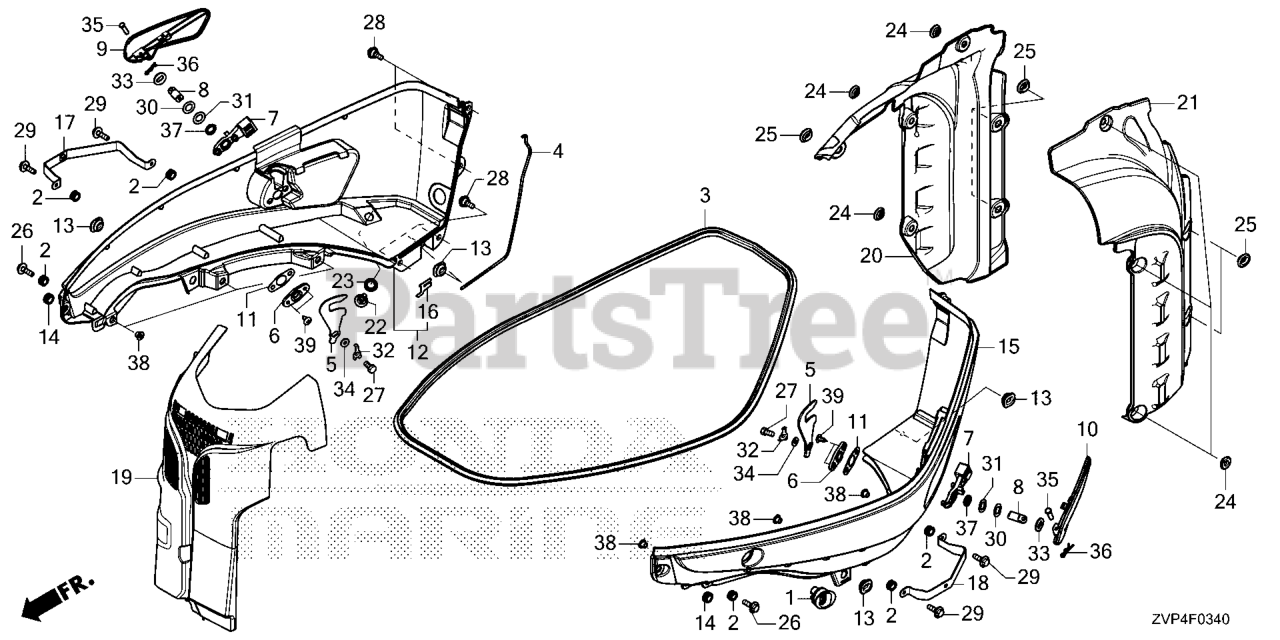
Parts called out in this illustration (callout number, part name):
1	GROMMET, PTT SWITCH
2	RUBBER, FENDER MOUNTING
3	SEAL, ENGINECOVER
4	SEAL, MID COVER R
5	HOOK, FR. COVER LOCK
6	HOLDER A, LOCK SHAFT
7	HOLDER B, LOCK SHAFT
8	SHAFT, COVER LOCK
9	LEVER *NH565*
9	LEVER *NHB14M*
10	LEVER *NH565*
10	LEVER *NHB14M*
11	SEAL, HOLDER A
12	COVER COMP *NH565*
12	COVER COMP *NHB14M*
13	GROMMET, MID COVER
15	COVER COMP *NH565*
15	COVER COMP *NHB14M*
17	BRACKET COMP (LOWER)
18	BRACKET COMP (LOWER)
19	COVER, FR.
20	COVER, RR.
22	GROMMET, WATER CHECK
24	GROMMET, SIDE COVER
25	GROMMET, AIR CLEANER HOUSING
26	BOLT-WASHER (6X22)
27	BOLT, HEX. (6X12) Use up to Frame SN 1005248.
28	BOLT, SPECIAL (6X17)
29	BOLT, FLANGE (6X25) (SUS-D)
30	WASHER, PLAIN RUBBER
31	WASHER (14MM)
32	WASHER, LOCK
33	WASHER, PIVOT
34	WASHER, PLAIN (6MM)
35	PIN (5X17.8)
36	PIN, LOCK (5MM)
37	OIL SEAL (14X20X3.2)
38	COLLAR, DISTANCE (6.2X7.5)
39	SCREW (5X14) (P0)
